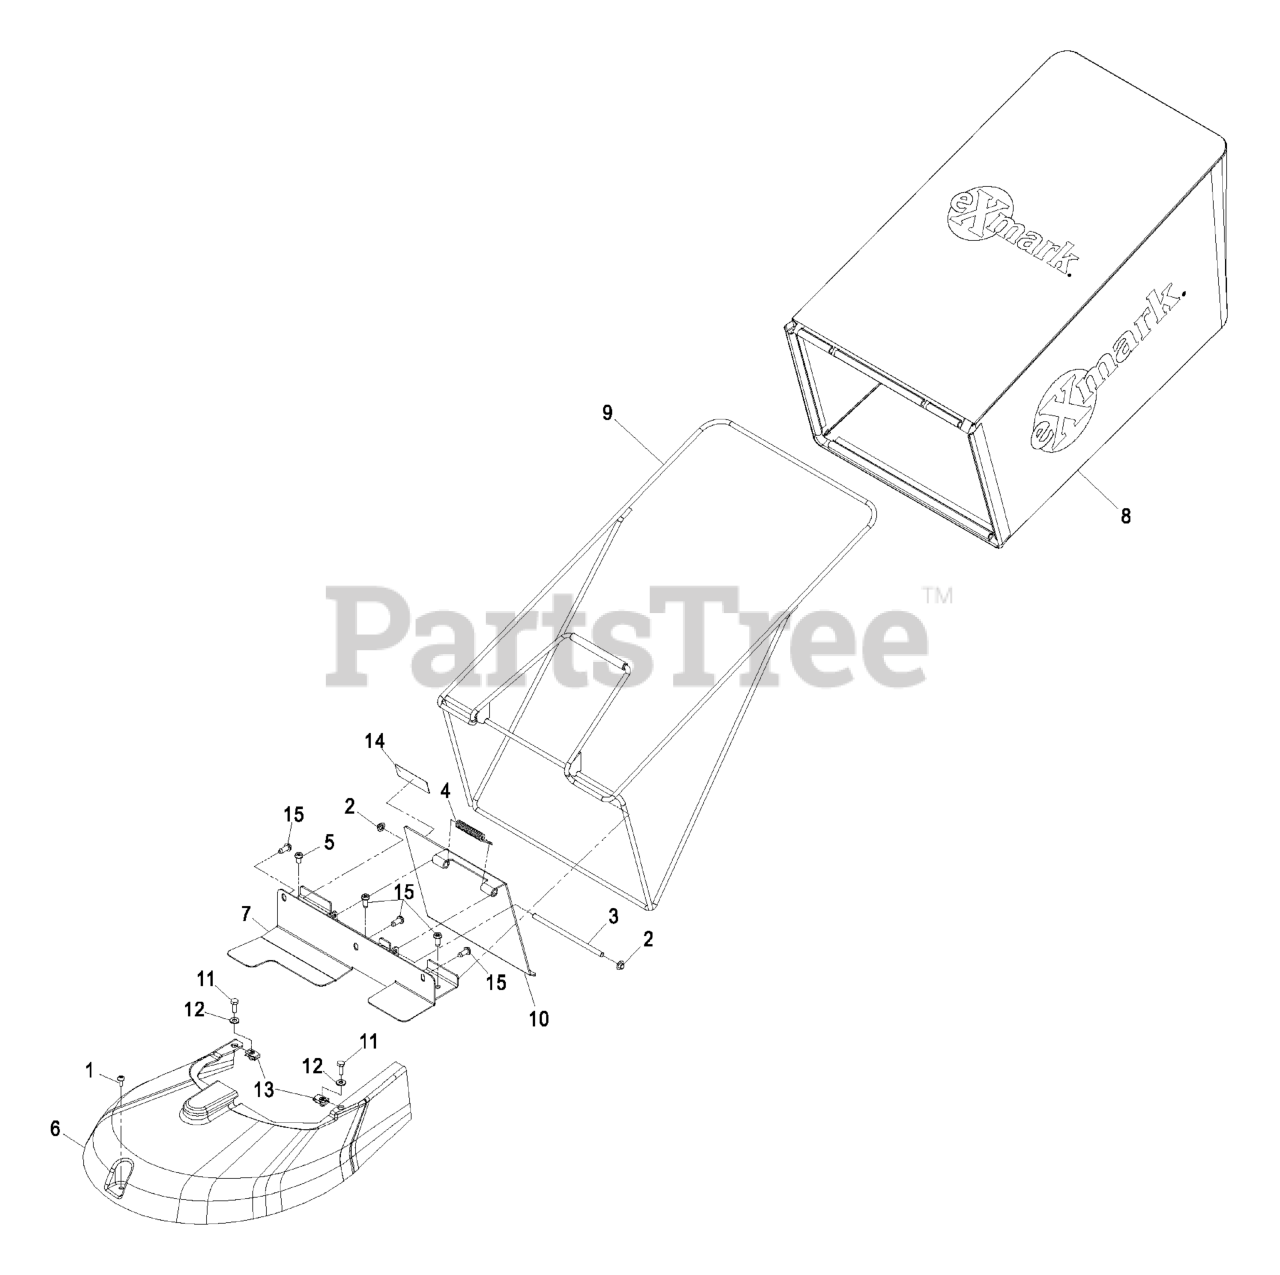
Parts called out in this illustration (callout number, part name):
1	SCREW-TP
2	NUT-PUSH
4	SPRING-TORSION
7	WLD,TANK/BAG MOUNT BRACKE
9	WLD,BAG FRAME
10	ASM,DOOR W/DECALS METRO 2
11	SCREW-HH
12	WASHER-FLAT
13	Nut, Retainer-Panel 1/4-20
15	SCREW-BHTF
